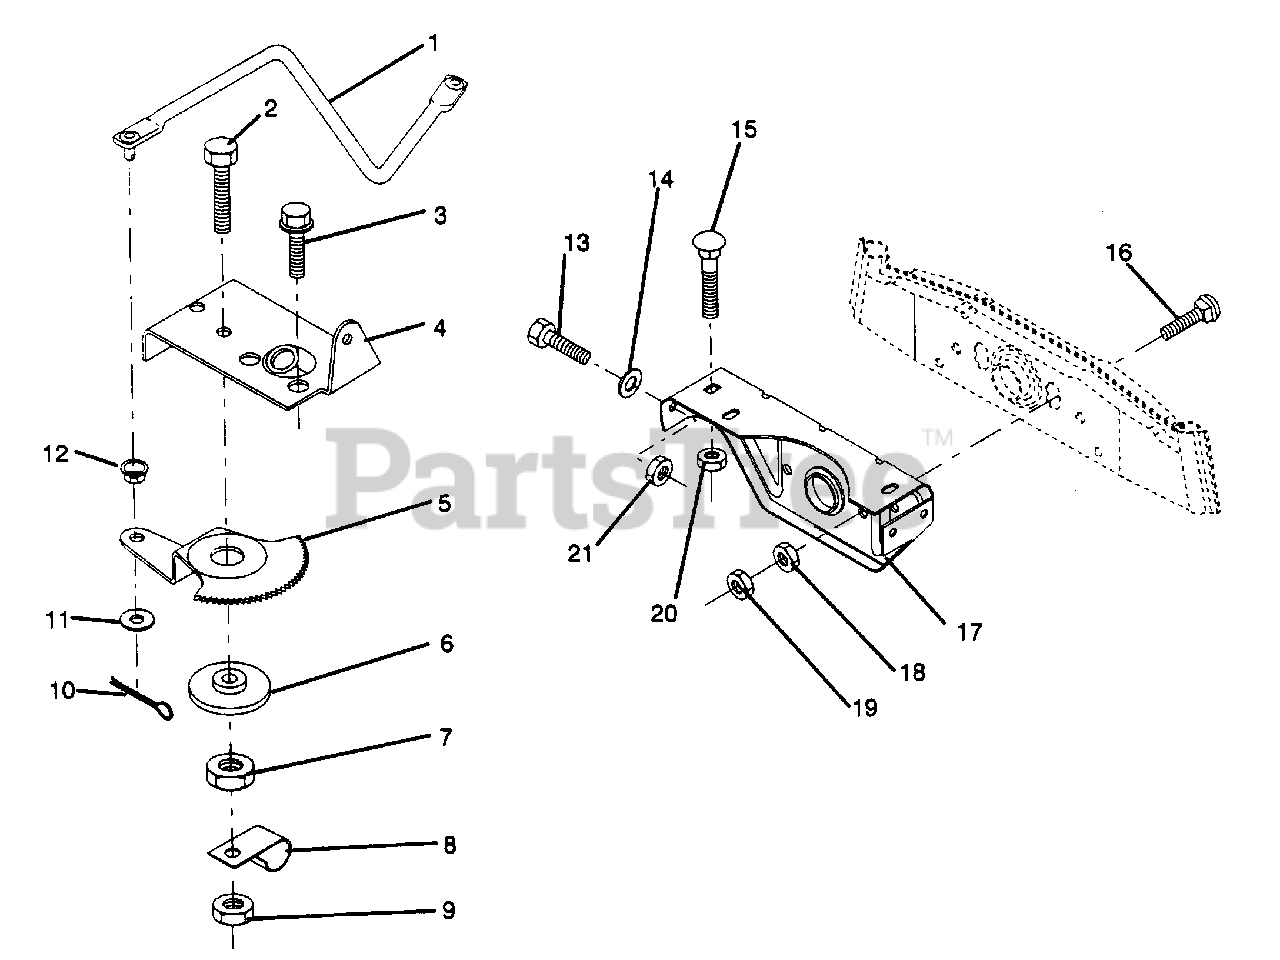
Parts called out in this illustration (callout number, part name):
1	Link, Drag (AYP part number)
2	Bolt, Fin. Hex 1/2-13 x 1 3/4 (AYP part number)
3	Screw Hex Thrdrol 5/16-18 x 1/2 (AYP part number)
4	Plate, Steering Support (AYP part number)
5	Gear, Sector (AYP part number)
6	Bushing (AYP part number)
7	Nut, Heavy Hex Top Lock 1/2-13 UNC (AYP part number)
8	Clip, Insulated (AYP part number)
9	Nut, Crownlock 3/8-16 (AYP part number)
10	Pin, Cotter 1/8 x 3/4 (AYP part number)
11	Washer, 13/32 x 13/16 x 16 Ga. (AYP part number)
12	Bushing (AYP part number)
13	Bolt, Hex Hd. 5/16-18 UNC x 3/4 (AYP part number)
14	Washer 11/32 x 7/8 x 16 Ga. (AYP part number)
15	Bolt, Carriage 3/8-16 UNC x 3/4 (AYP part number)
16	Bolt, Carriage (AYP part number)
17	Support, Front Axle (AYP part number)
18	Nut, Fin. Hex 3/8-16 UNC (AYP part number)
19	Nut, Centerlock 3/8-16 UNC (AYP part number)
20	Nut, Crownlock 3/8-16 UNC
21	Nut, Crownlock 5/16-18
